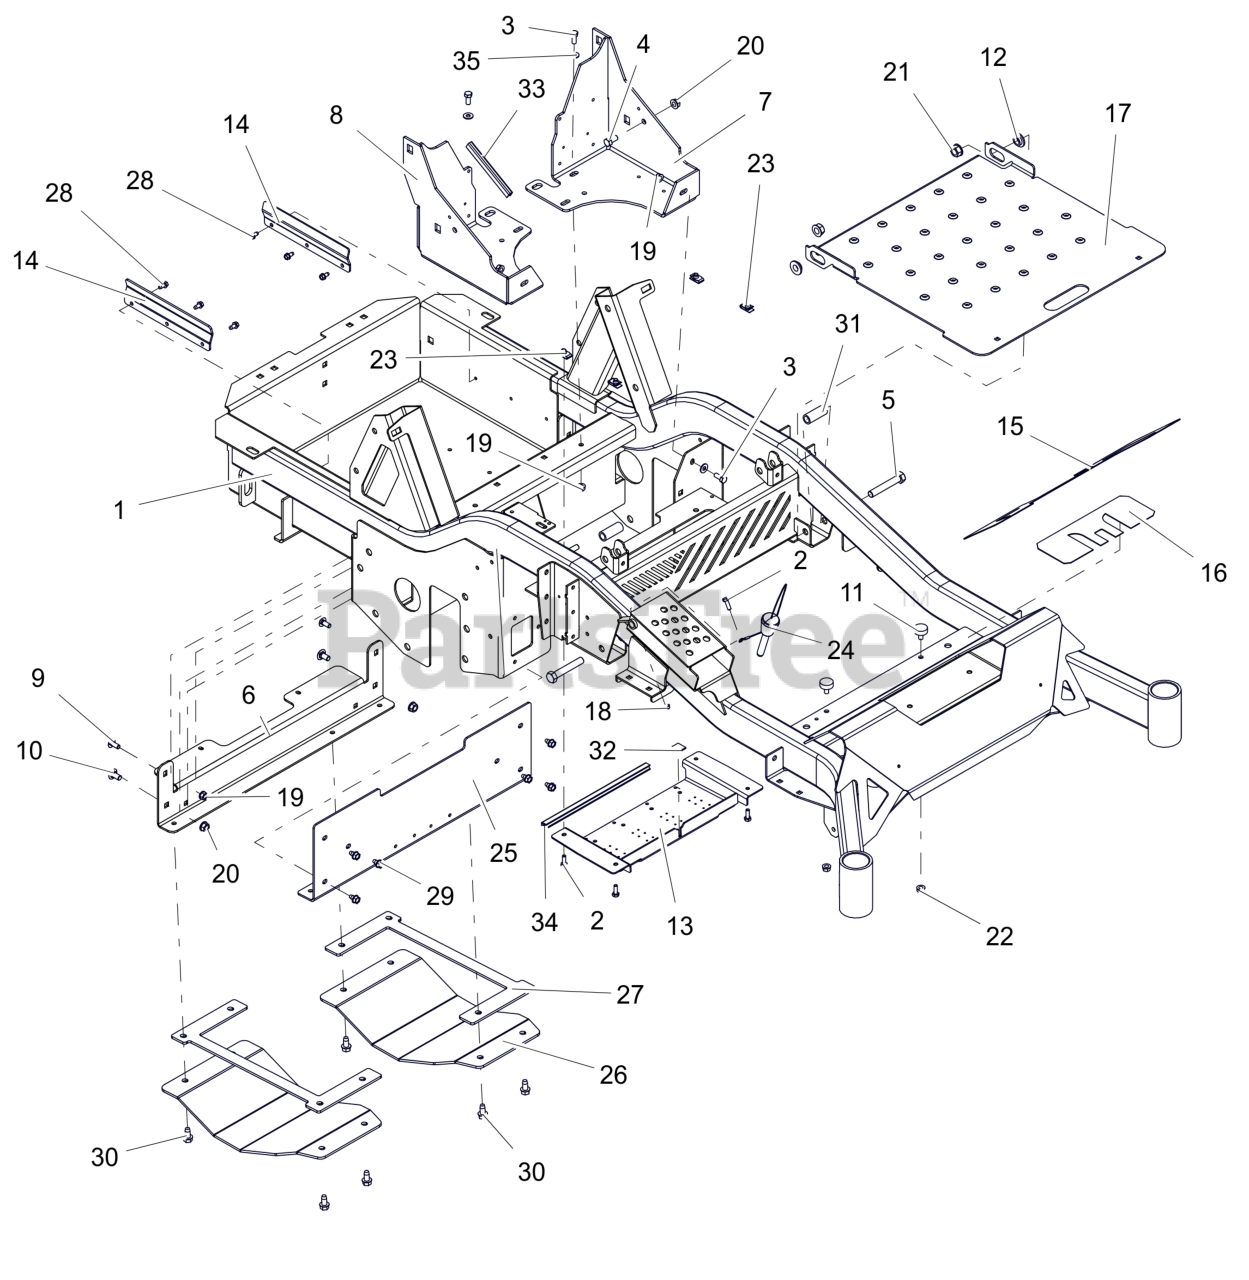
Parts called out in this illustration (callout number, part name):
1	KIT,EV FRAME(SM)W/DECALS-A
2	BLT, HEX .25-20X.75 G5 ZCC
3	BLT,HEX .31-18X.75 G5 ZCC
4	BLT,HEX .38-16X.75 G5 ZCC
5	BLT, HEX .50-13X3.00 G5 ZCC
6	BRKT, SKID PLATE MTG. (ORANGE)
7	BRKT, SUPPORT ROPS -LH (ORANGE)
8	BRKT, SUPPORT ROPS-RH (ORANGE)
9	BLT, RHSSN.31-18X.750 G5 ZCC
10	BLT, RHSSN .38-16X.75 G5 ZCC
11	BUMPER, RUBBER
12	BSHG-FLG .515X.750X.395X1.120
13	COVER, BOTTOM ACCESS -OPEN (ORANGE)
14	DEFLECTOR, BATTERY -EV (ORANGE)
15	GRIP, FRONT
16	GRIP, TAPE FRONT
17	PANEL, ACCESS
18	NUT-LK-CTR-FLG .25-20 ZC120
19	NUT,LK-CTR-FLG .31-18 GF ZCC
20	NUT-LK-CTR-FLG .375-16 GF ZCC
21	NUT-LK-CTR-FLG .500-13 GG ZCC
22	NUT,SPNLK-FLG .31-18 G5 ZCC
23	NUT-RTNR .25-20X.56
24	PIN, MAGNETIC .50X2.50
25	PLATE, FRONT FRAME (ORANGE)
26	PLATE, SKID (BLACK)
27	PLATE, SKID TENSION (BLACK)
28	SCR-TAP .25-20X.50 HWH ZCC
29	SCR,TAP .312-18X.50 HWH TR ZCC
30	SCR,TAP .375-16X.75 HWH TR ZCC
31	SPACER, .515X.75X1.83
33	STRIP, COWL
34	STRIP, COWL
35	WSHR, FLT .312X.734X.065 ZCC
